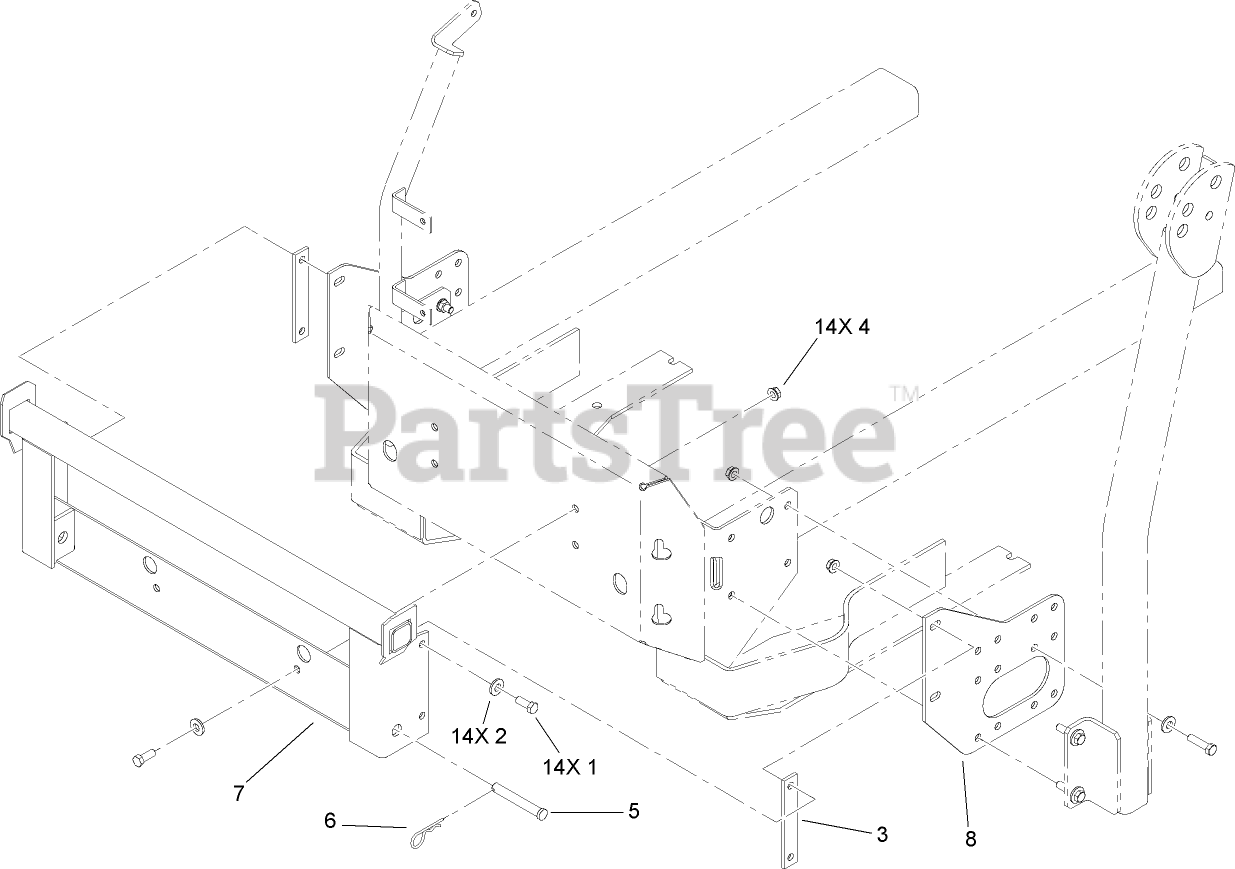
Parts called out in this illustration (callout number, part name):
1	SCREW-HH
2	WASHER-BELLEVILLE
4	NUT-HHF, WHIZ
5	PIN-CLEVIS
6	PIN-COTTER
7	MOUNT-BAGGER
8	PLATE-MOUNT, BAGGER
